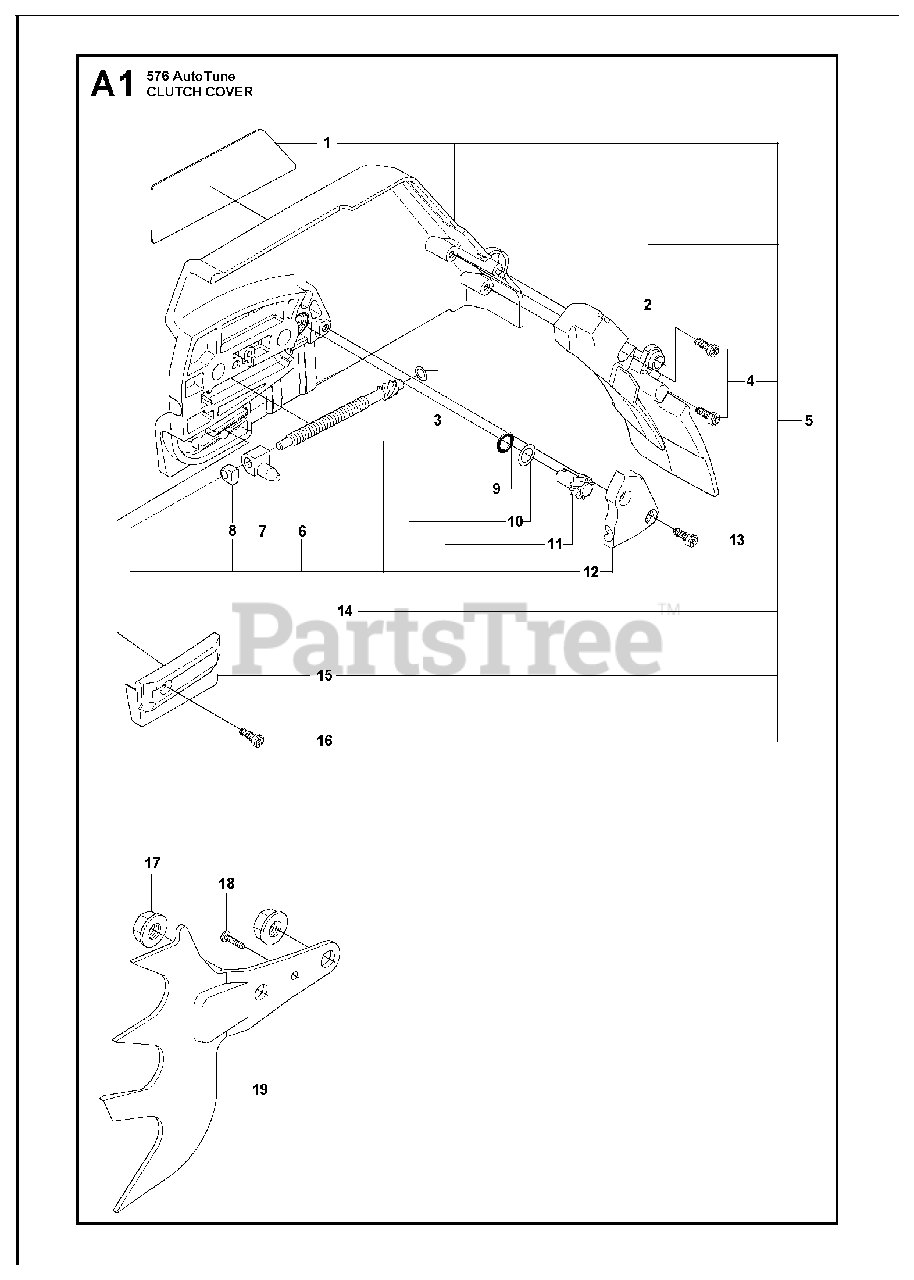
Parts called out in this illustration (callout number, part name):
1	DECAL
2	PROTECTOR
3	WASHER
4	SCREW
5	CLUTCH COVER ASSY
6	WORM SCREW / ADJUSTER
7	PAWL
8	SLEEVE
9	O-RING
10	WASHER
11	RP ADJUSTER
12	COVER
13	SCREW
14	KIT-CHAIN TENSIONER
15	CHAIN GUIDE
16	SCREW
17	NUT M8 FLANGE
19	FELLING DOG
